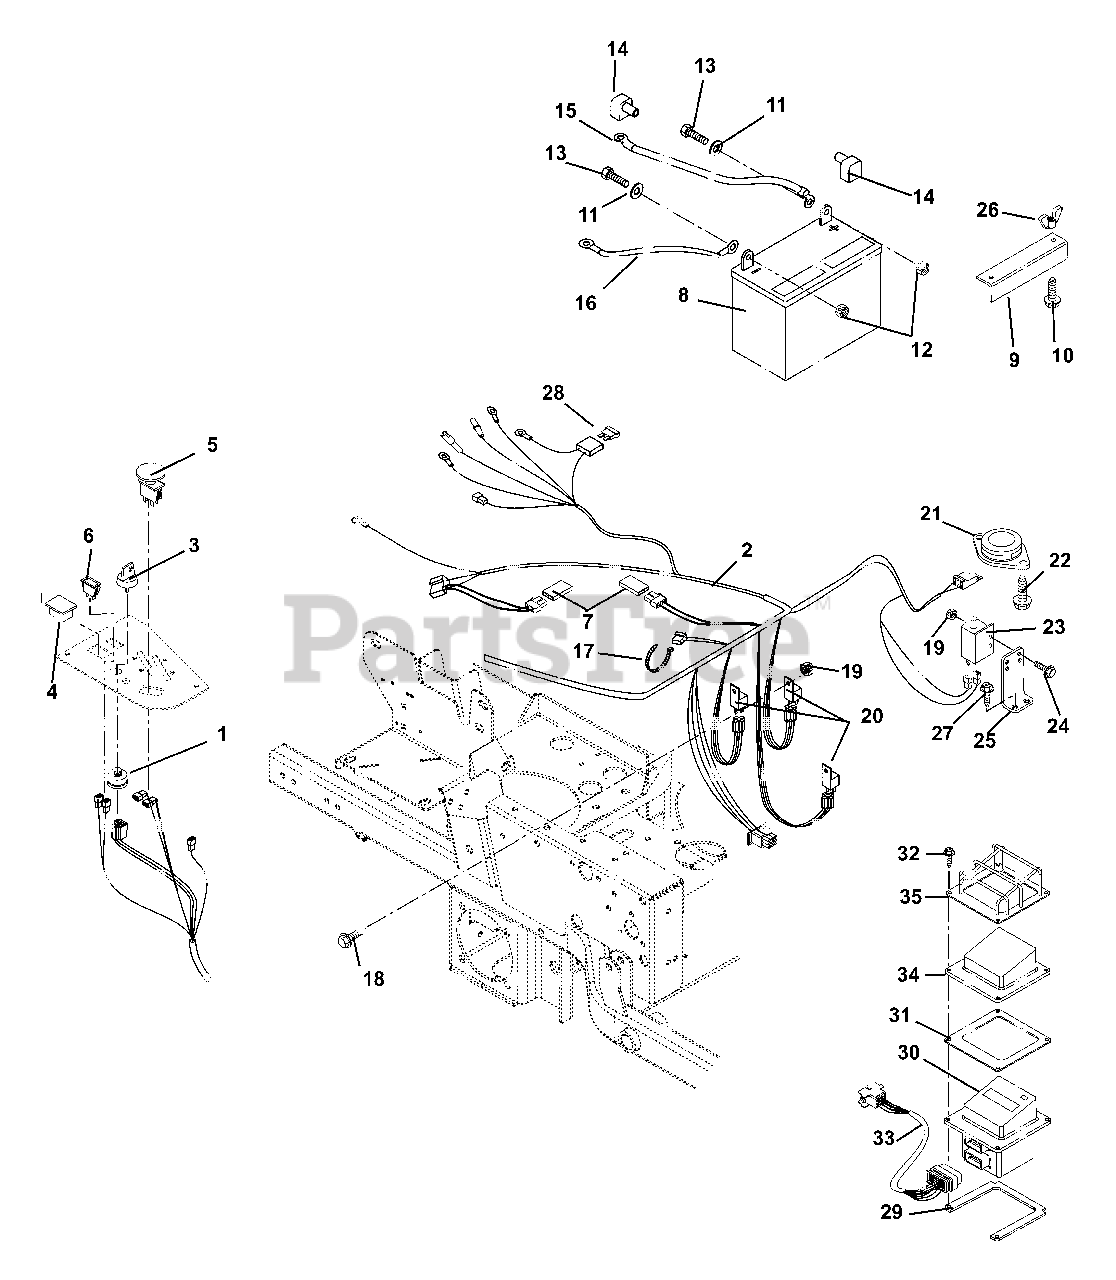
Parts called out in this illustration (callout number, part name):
1	SWITCH, IGNITION
2	HARNESS, IZ & MONST. EYE-Q
3	KEY, W/ SHIELD
4	PLUG, HOUR METER
5	SWITCH, CLUTCH
6	LIGHT,INDICATOR
7	DIODE, CONNECTOR SHELL
8	BATTERY, 300 CCA 10U1L
9	HOLD DOWN
10	BLT-RDHDSQNK .25-20X7.50 GR2YZ
11	@WSHR-FL-STL.281X.62X.065 YWZC
12	@NUT-LK-TOP-FLG .25-20 YWZC
13	@BLT-HEX .25-20X.75 GR5 YWZC
14	INSULATOR
15	CABLE, POSITIVE BATTERY 26.00
16	CABLE, NEGATIVE BATTERY 24.00
17	CABLE TIE LG 5-1/2
18	@SCR-MCH 10-24X.50 HWH YWZC
19	@NUT-LK-NYL 10-24 W/INSRT YWZC
20	RELAY
21	SEAT SWITCH
22	@SCR-TAP 12-24X.50 HWH TR YWZC
23	SWITCH- SINGLE POLE N.O.
24	@SCR-MCH 10-24X.75 HWH YWZC
25	BRAKE SWITCH MOUNT - BLACK
26	NUT-LK WING .250-20 YWZC
27	@SCR-TAP .25-20X.50 HWH TR YWZ
28	FUSE, 30 AMP.
29	SPACER, ENCLOSURE MTG. (BTM)
30	ASSY, EYE-Q
31	GASKET-EYE Q
32	SCR-MCH 10-24X1.0 SL PAN BLACK
33	HARNESS, EYE-Q
34	GUARD, ELEMENT
35	GUARD, VINYL EYE-Q
